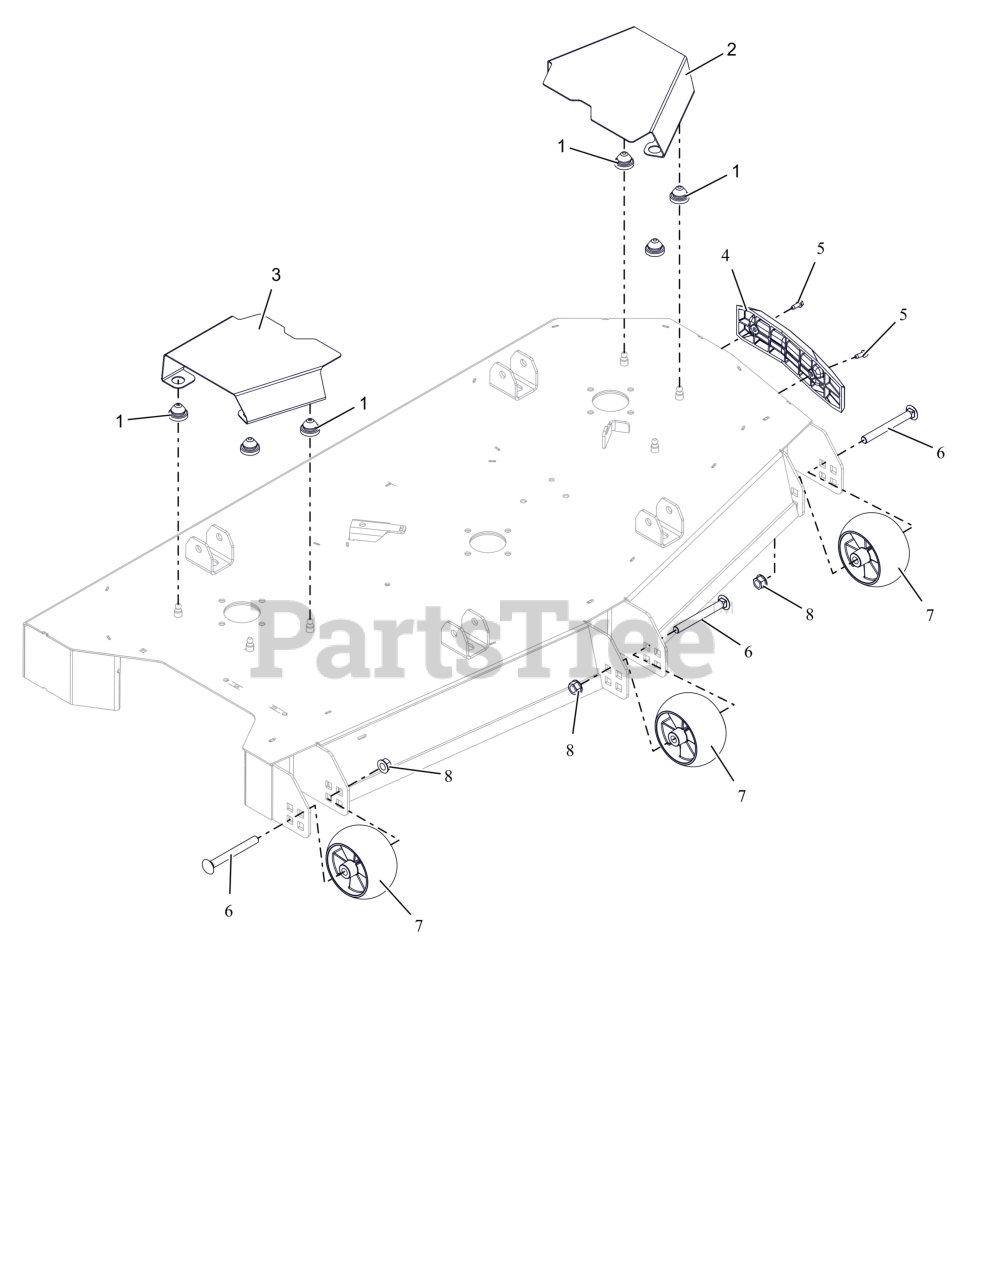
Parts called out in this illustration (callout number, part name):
1	COUPLING, RUBBER PUSH-IN
2	COVER- BELT
3	COVER- RIGHT BELT
4	BUMPER- DECK
5	SCR,TAP .25-20X.625 HWH ZCC
6	BLT,RHNS .50-13X4.50 G5 ZCC NS
7	WHEEL, ANTI SCALP - 5X3 CTR W/RIBS
8	NUT-LK-CTR-FLG .500-13 GG ZCC
